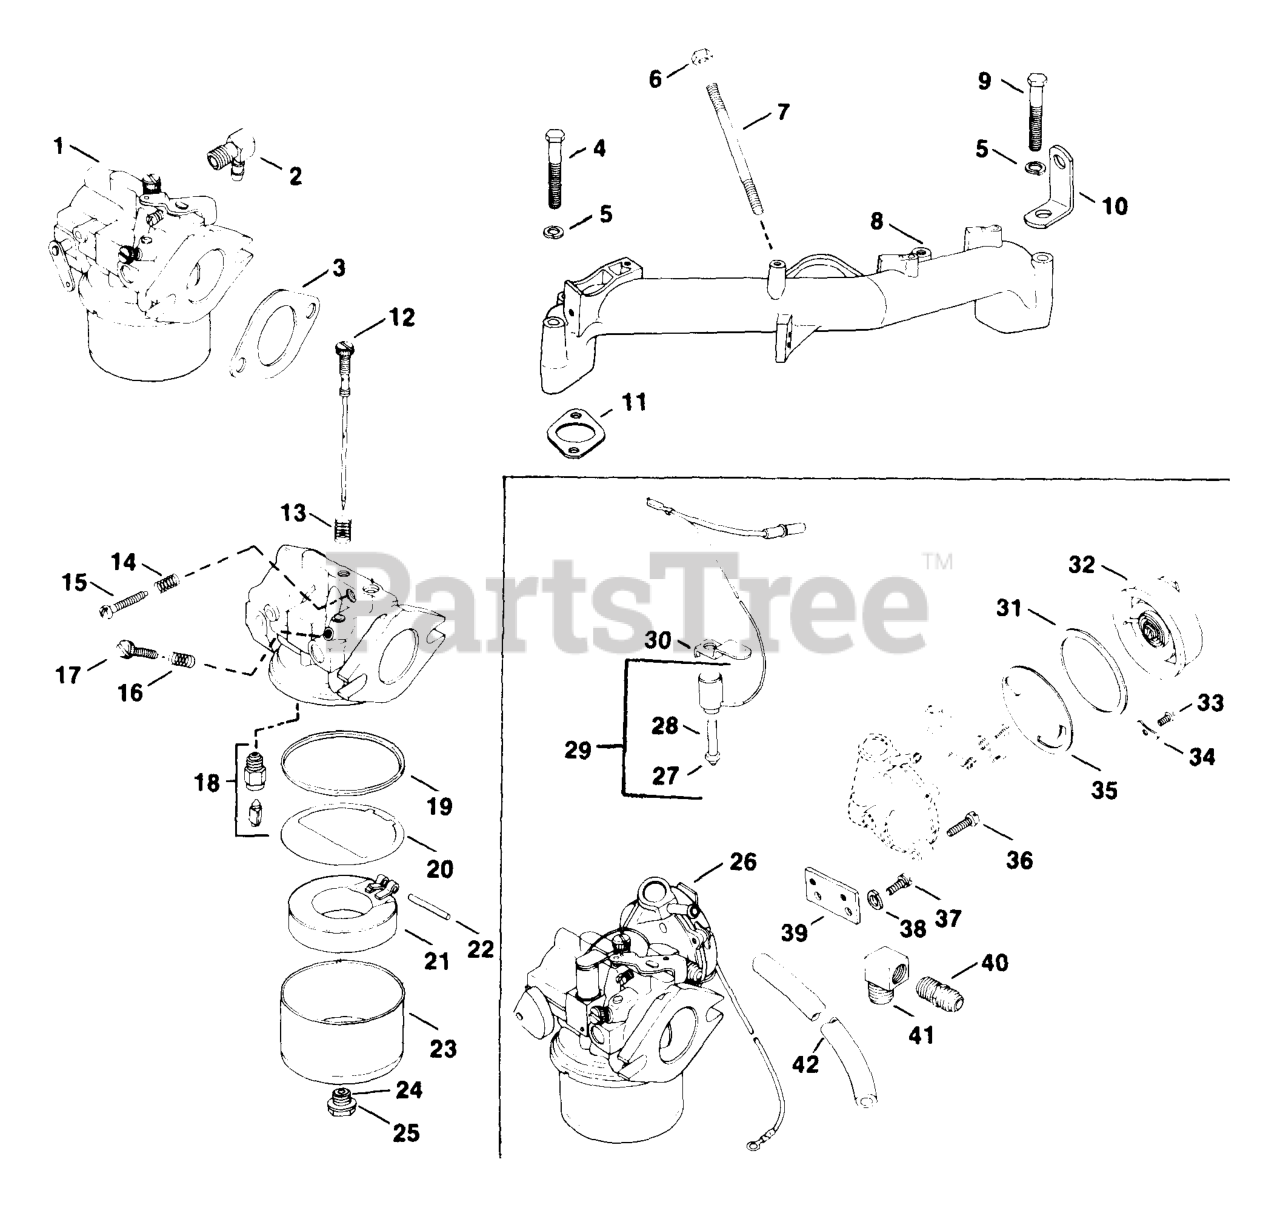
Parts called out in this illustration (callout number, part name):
2	HOSE - USE 25 155 02
3	GASKET, CARBURETOR
4	Screw, H.C. 5/16-18 x 2-3/4
5	Washer, lock 5/16
6	Nut, hex. jam 5/16-18
7	STUD, 5/16-18X1" USE 25 072 06-S
8	MANIFOLD - USE 52 164 06
9	Screw, H.C. 5/16-18 x 2-7/8
10	STRAP - DISCONTINUED
12	NEEDLE - DISCONTINUED
15	SCREW, SPECIAL
16	SPRING-(#DSC)
17	SCREW - DISCONTINUED
18	Fuel inlet needle & seat
19	GASKET
20	Gasket, bowl baffle
21	Float Kit
22	PIN
24	NUT - DISCONTINUED
26	Kit, carburetor repair
